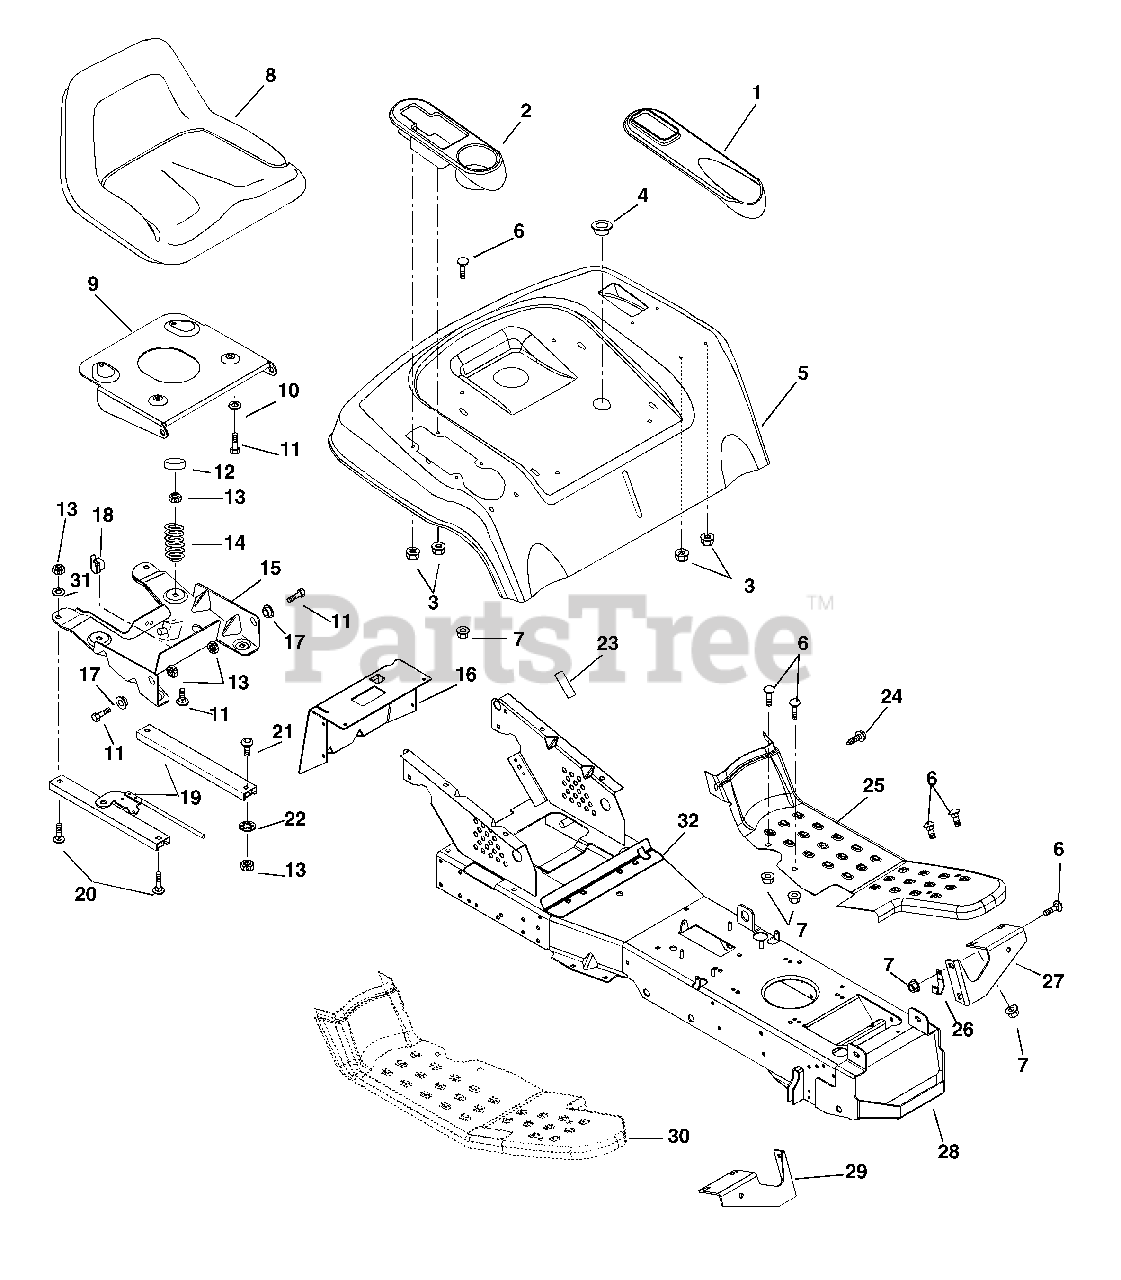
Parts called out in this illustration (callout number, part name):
1	INSERT- LIFT
2	INSERT - BEVERAGE
3	NUT-SELF-THRDNG FITS.25 STUDPL
4	SNAP BUSHING
5	REAR DECK
6	@BLT-RHDSSQNK .31-18X.62 G5YZ
7	@NUT-SPNLK-FLG .312-18 YWZC
8	SEAT V-1500 HI WELTLESS
9	PLATE, SEAT PIVOT
10	WSHR-LK .312X.097 HVY YWZC
11	@BLT-HEX .31-18X.75 GR5 YWZC
12	TUBE CAP
13	@NUT-LK-CTR .31-18 YWZC
14	SG-COMP .148X1.23X2.41 WLD87
15	SEAT BOX
16	DRAWBAR
17	BSHG-FLG .325X.465X.333X.685
18	CLIP-HARNESS TINNERMAN
19	SEAT SLIDES -(RAME TAK-3010-4)
20	BLT-RDHDSQSHK.31-18X.75 GR2 YW
21	SCR-CAP BTHD.31-18X.50 GR5 YZ
22	WSHR-LOCK INT .31 YWZC
23	PAD, FOAM
24	@SCR-TAP .31-18X.50 HWH TR YWZ
25	FOOT REST L.H.
26	J-CLAMP
27	BRACE, FOOT REST LH
28	FRAME, MAIN (WELDMENT)
29	BRACE, FOOT REST RH
30	FOOT REST RH
31	@WSHR-LK .31X.078 REG YWZC
32	PLATE, REINFORCING
